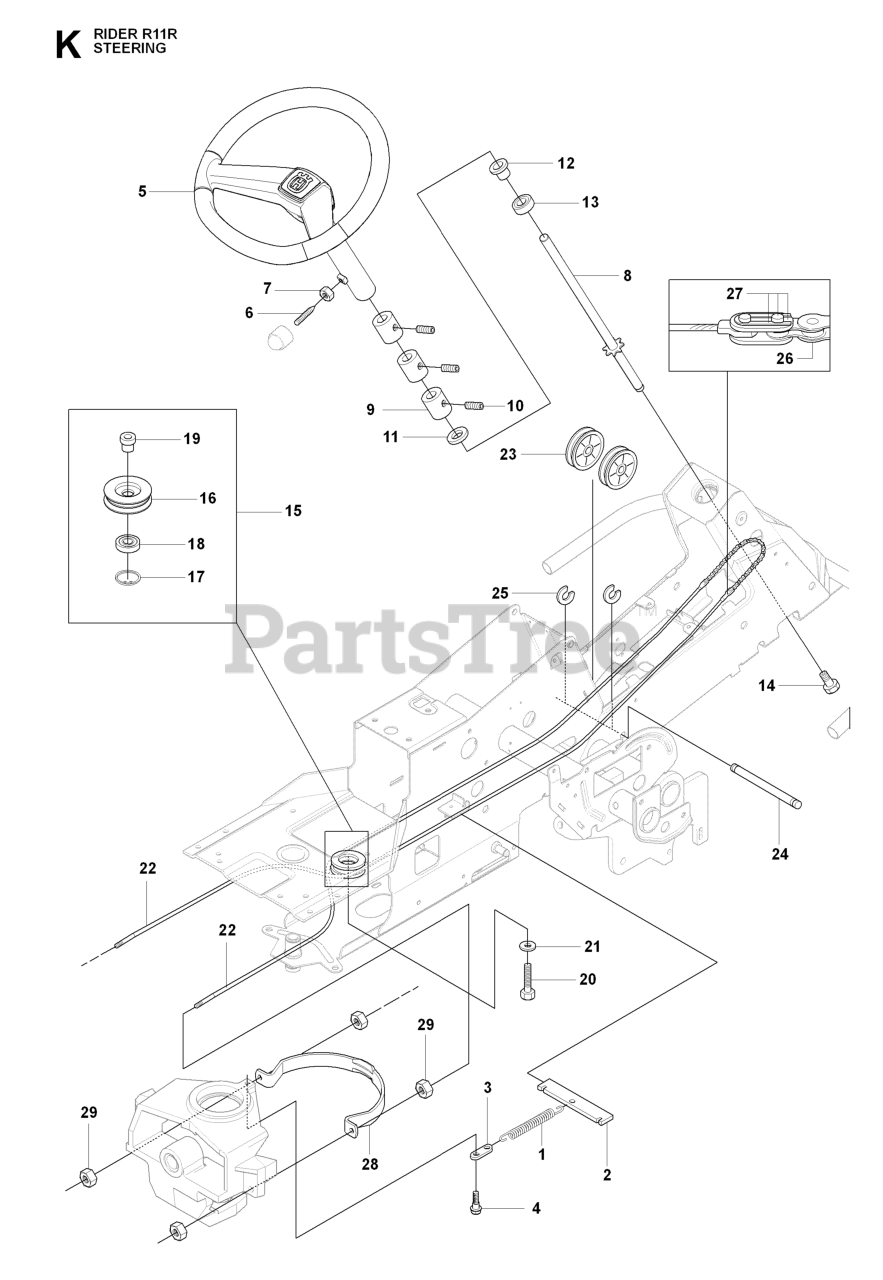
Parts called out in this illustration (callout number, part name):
2	SPRING BRACKET
5	STEERING WHEEL
7	NUT
8	ROD STEERING ASSY
9	SPACER
13	BALL BEARING 6004-2RS1
17	CIRCLIP SGH 47
18	BALL-BEARING 6204-2RS
22	RP STEERING CABLE COMPLETE
25	RETAINING RING
26	STEERING CHAIN
28	WIRE GUIDE
29	NUT
